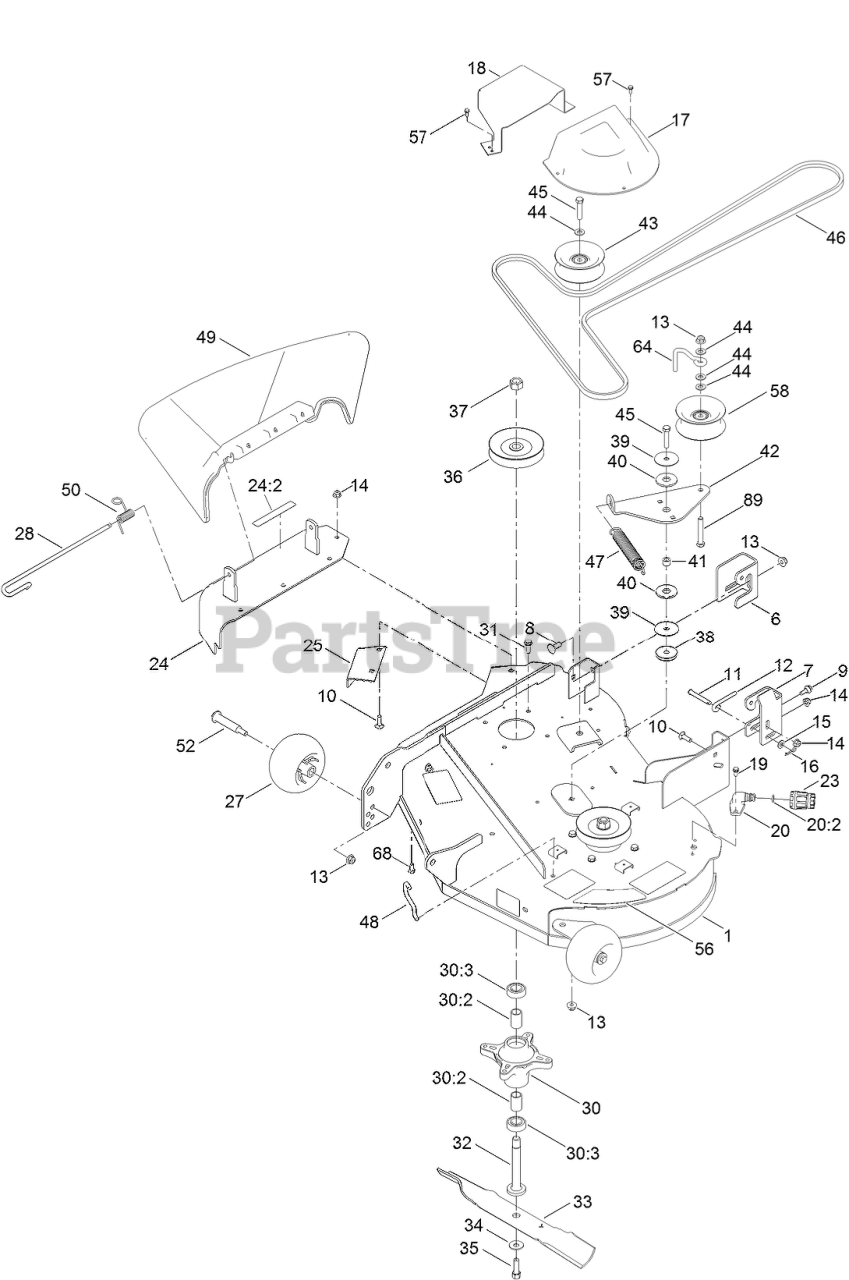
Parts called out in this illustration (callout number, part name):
1	34 INCH DECK AND DECAL ASM
6	BRACKET-HANGER, RH
7	BRACKET-HANGER, LH
8	BOLT-CARR
9	SCREW-SHOULDER,HWH
10	SCREW-CARR
11	PIN-CLEVIS
12	ROD-LEVEL, DECK
13	NUT-HF, NI
14	NUT-HF, NI
15	WASHER-PLAIN
16	PIN-COTTER
17	COVER-BELT
18	COVER-DECK BELT
19	SCREW-HWH
20	FITTING-WASHOUT
20:2	O-RING
23	CONNECTOR-HOSE
24	COVER ASM W/DECAL
24:2	DECAL-DANGER
25	BAFFLE-CUTOFF
27	ROLLER-SCALP, ANTI
28	PIN-CHUTE
30	SPINDLE ASM
30:2	SPACER
30:3	BEARING-BALL
31	SCREW-TAPTITE
32	SHAFT-SPINDLE
33	BLADE-HI LIFT
34	WASHER-BELLEVILLE
35	SCREW-HH
36	PULLEY ASM
37	NUT-HEX
38	WASHER-PLAIN
39	WASHER
40	WASHER-FRICTION, COMPOSITE
41	SPACER
42	ARM-IDLER
43	PULLEY-IDLER, FLAT
44	WASHER-FLAT
45	SCREW-HH
46	BELT-V
47	SPRING-EXTENSION
48	HOOK-RETURN, SPRING
49	DEFLECTOR-DISCHARGE
50	SPRING-TORSION
52	BOLT-SHOULDER
56	DECAL-DECK
57	SCREW-TAPTITE
58	PULLEY-IDLER,FLAT
64	GUIDE-IDLER, BELT
68	SCREW-HH
89	SCREW-HH
